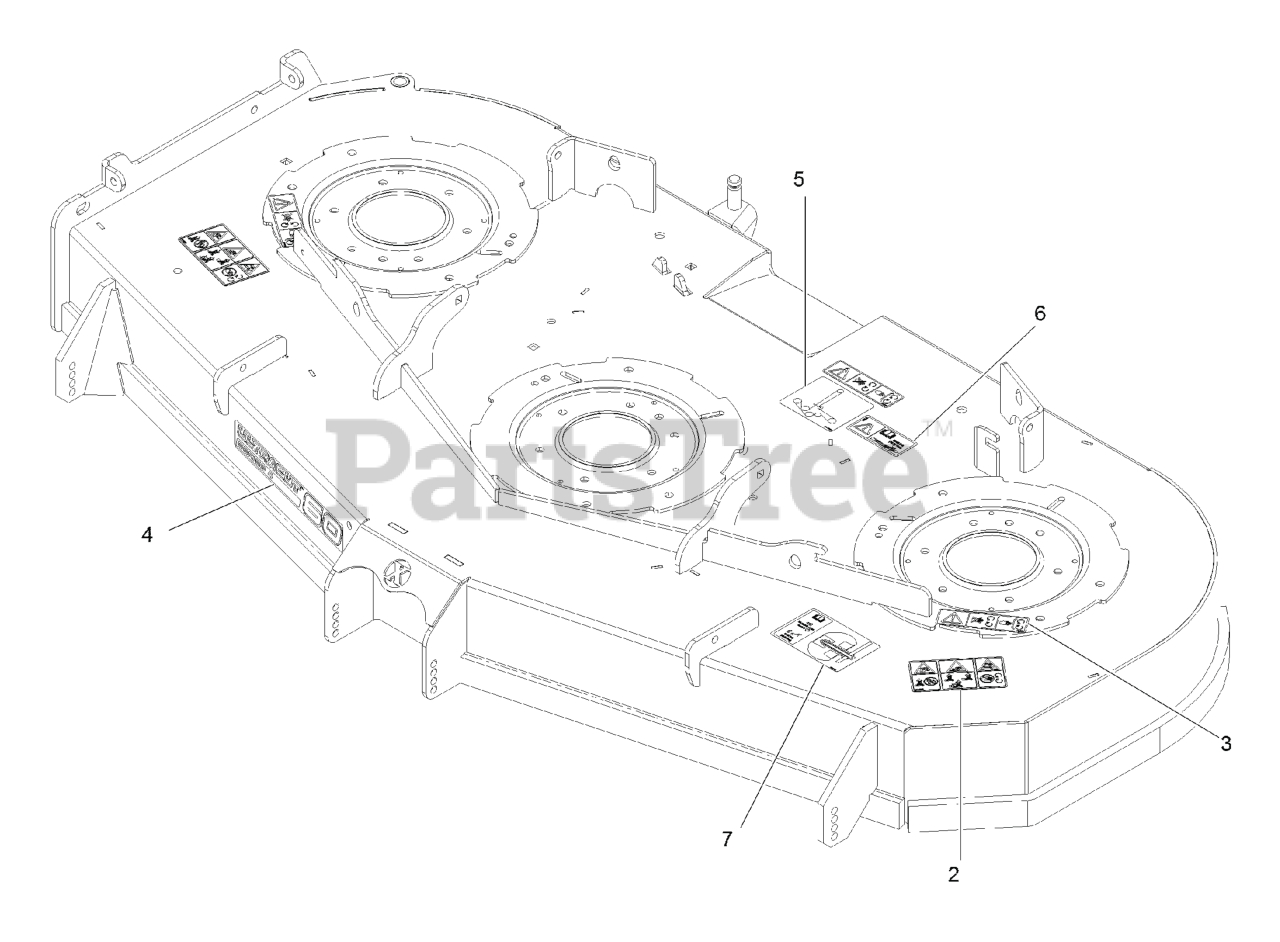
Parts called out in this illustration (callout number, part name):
2	DECAL-WARNING THROWN OBJ
3	DECAL-COVER, MISSING
4	DECAL, 604
5	DECAL-BELT ROUTING
6	DECAL-TORQUE, BOLT
7	DECAL-ROLLER MOUNTING
